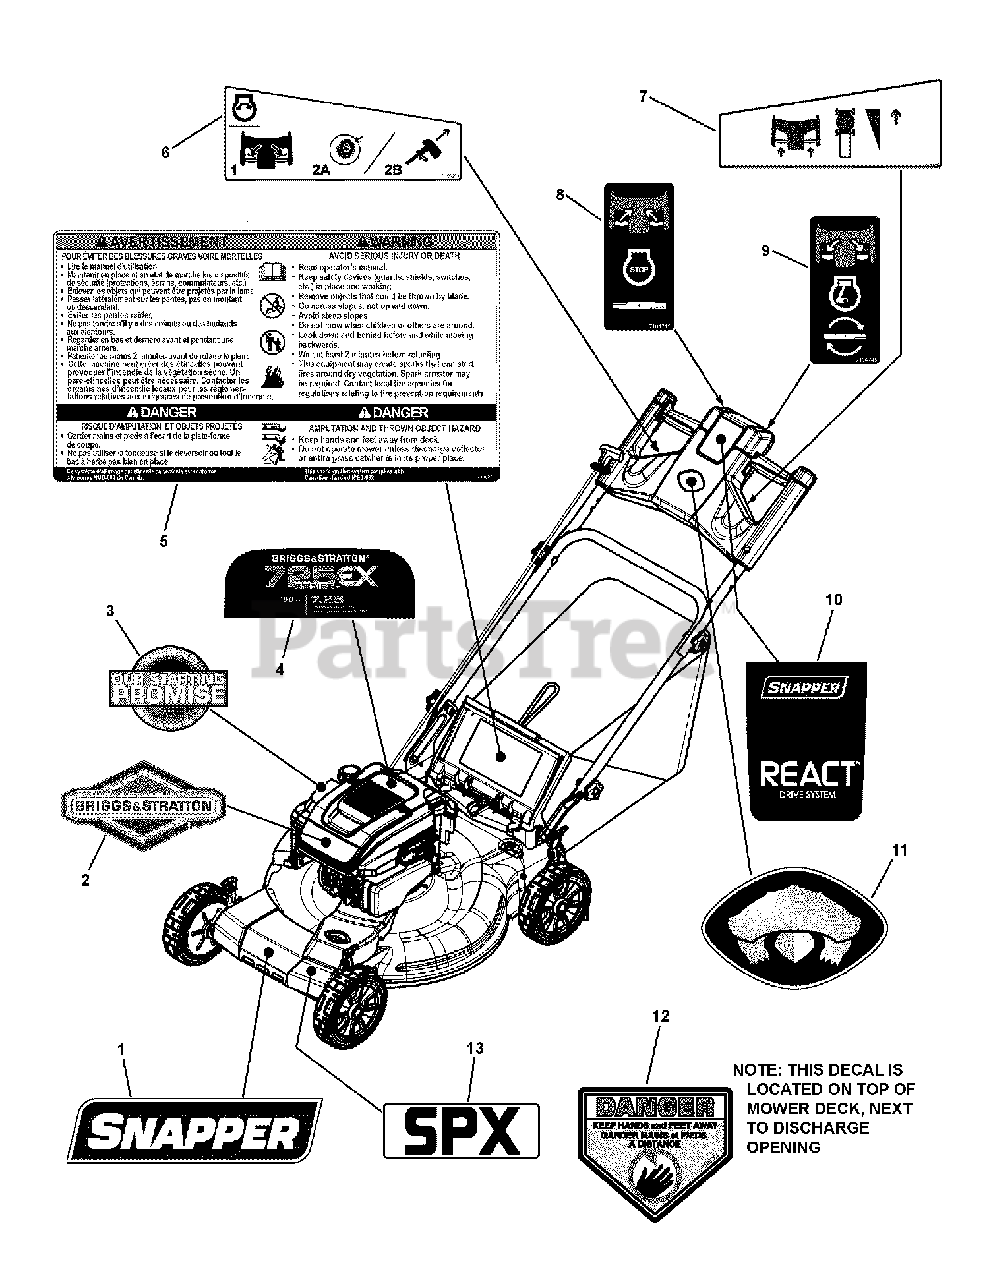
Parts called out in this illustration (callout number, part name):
1	DECAL, Front Shroud, Snapper Logo
2	LABEL, Briggs & Stratton Logo
3	LABEL, Starting Promise
4	DECAL, 725 Series Engine
5	DECAL, Warning/Danger, French/English
6	DECAL, Start Button/Rope, React
7	DECAL, Drive, React
8	DECAL, Stop, React
9	DECAL, Run, React
10	DECAL, Handle, React Drive
11	DECAL, Snapper Turtle
12	DECAL, CPSC, French/English
13	DECAL, Front Cover, SPX Series
